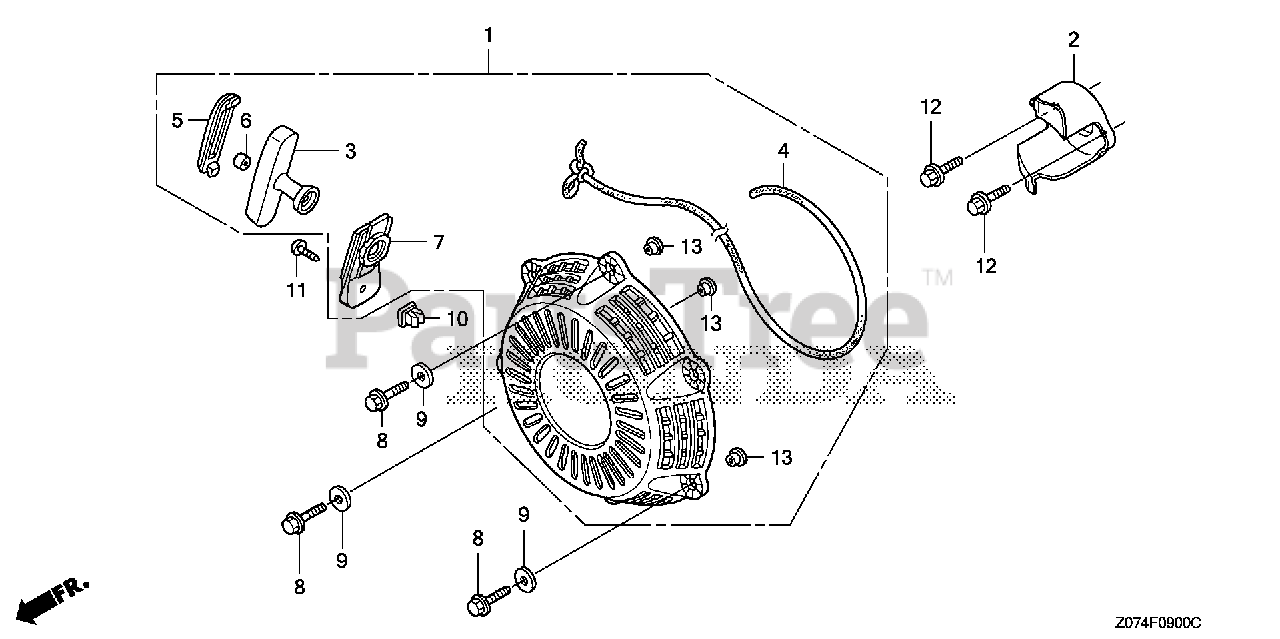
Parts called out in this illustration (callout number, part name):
1	STARTER ASSY., RECOIL
2	PULLEY, STARTER
3	GRIP, STARTER
4	ROPE, STARTER
5	COVER, GRIP
6	GRIP, REINFORCEMENT
7	GUIDE, STARTER ROPE
8	BOLT, FLANGE (6X20) (CT200)
9	WASHER, PLAIN (6.5X15)
10	GROMMET, SCREW (6MM)
11	SCREW, TAPPING (5X16) (PO)
12	BOLT, FLANGE (6X12) Use from Engine SN 2086984.
13	COLLAR, RECOIL STARTER
